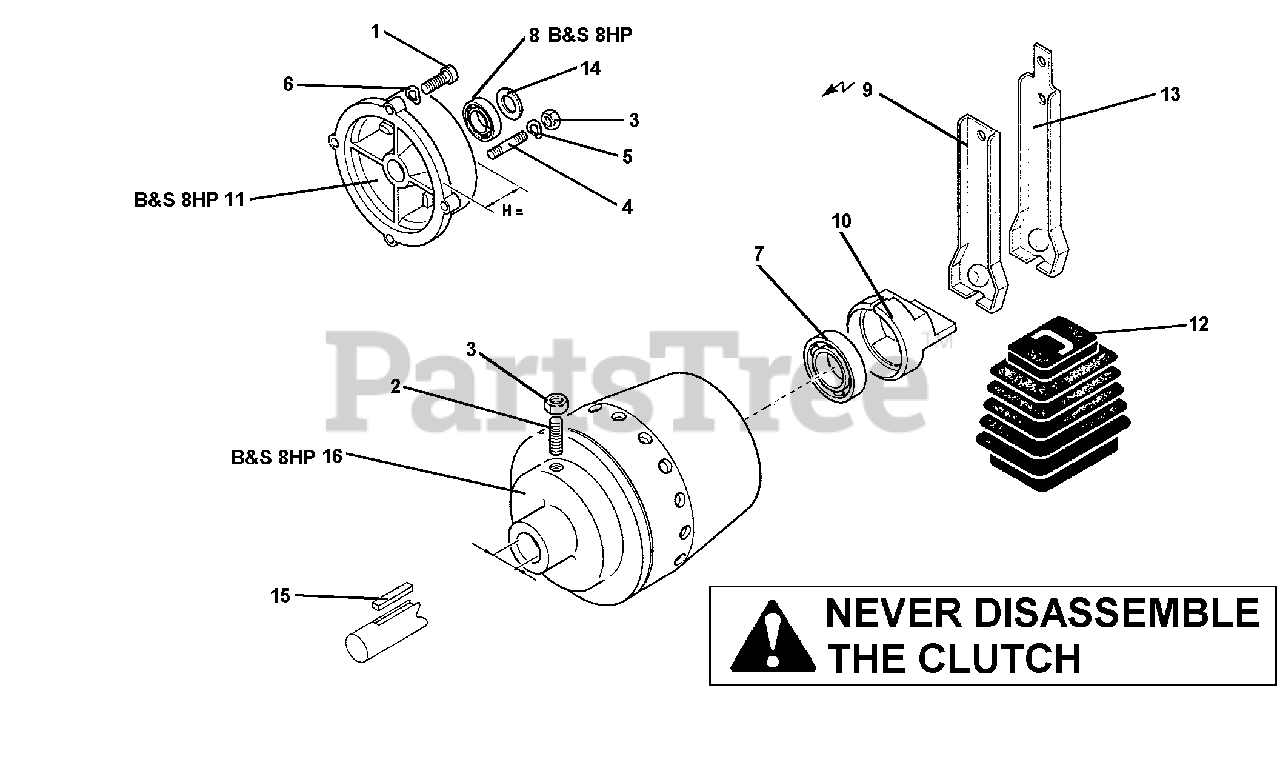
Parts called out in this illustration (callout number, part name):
1	SCREW 3/8X1"
2	SCREW M8X30
4	STUD, M8X40X14X14
5	WASHER, WAVE
6	WASHER, WAVE
7	BEARING, M17X40X12
8	BEARING, 30X55X13
9	CLUTCH LEVER, ELECTRIC START
10	CONE PUSHER
11	FLANGE, 8HP & 9HP B&S
13	LEVER, RECOIL START
16	CLUTCH, 8HP & 9HP B&S
